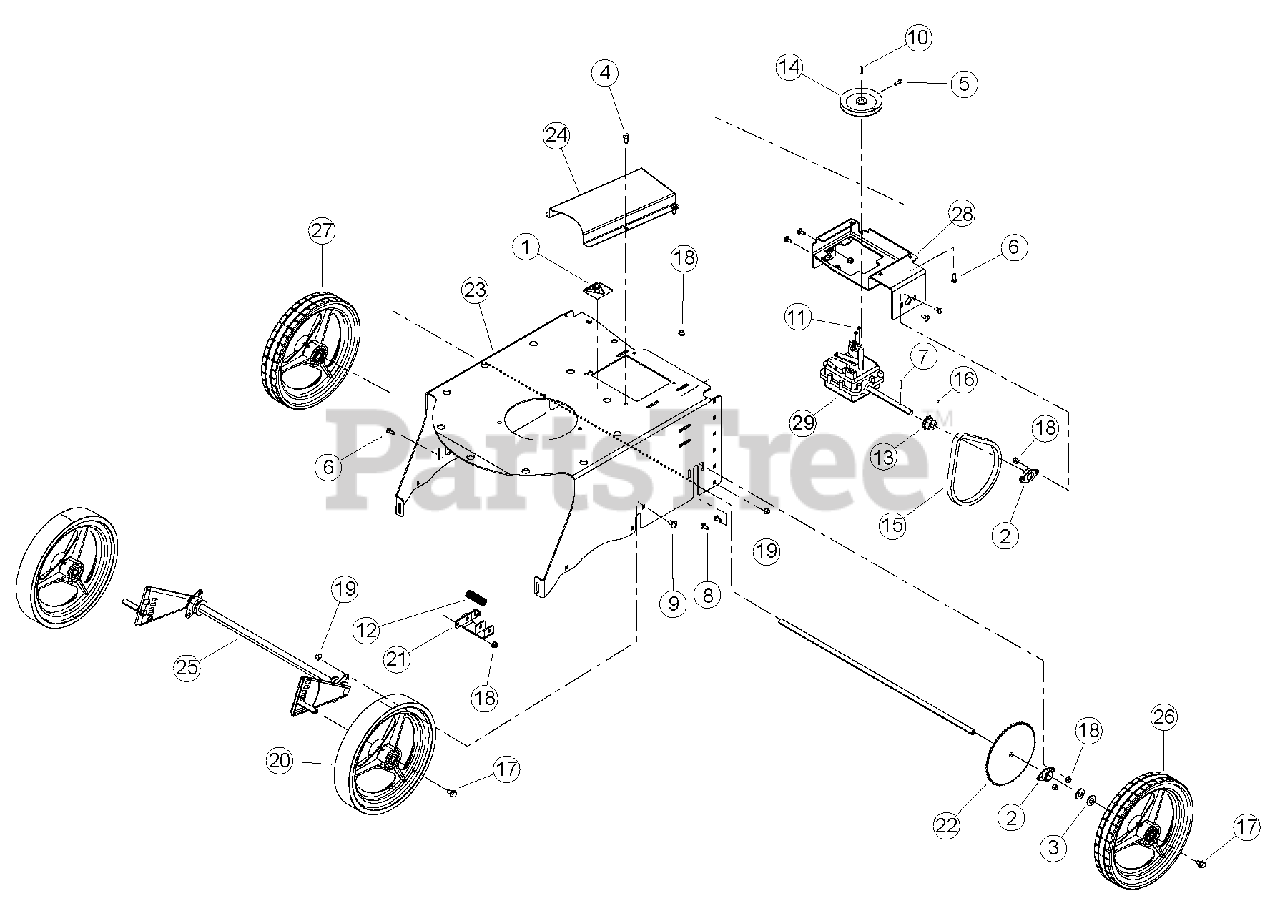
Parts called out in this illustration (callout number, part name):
1	DECAL, SHIELD DANGER
2	BEARING, 1/2 FLANGE
3	WASHER, 1/2 SAE FLAT
4	SCREW, 11/32 X 7/8 HWH AB THREAD
5	SCREW, 1/4 X 5/8 SQ HD SET
6	BOLT, 1/4 X 3/4 CRG
7	PIN, 1/8 X 7/8 SPRING
8	BOLT, 1/4 X 5/8 CRG
9	BOLT, 5/16 X 5/8 CRG
10	KEY, 4 MM SP X 20 MM
11	WASHER, #6 SAE FLAT
12	SPRING, COMPRESS LC-072J-6
13	SPROCKET, 35 B10
14	PULLEY, 4 O.D. X 12 MM BORE
15	CHAIN, #35 X 62 PITCH W/ CONN. LINK
16	SCREW, #8-32 X 3/16 KNR CUP PT
17	BOLT, 5/16-18 X 1/2 GR5 HH SER/FLN
18	NUT, 1/4-20 NYLOCK FLANGE
19	NUT, 5/16-18 NYLOCK FLANGE
20	WHEEL ASSEMBLY, BEARVAC PUSH
21	WELDMENT, BEARVAC HEIGHT ADJ.
22	WELDMENT, SP LONG AXLE
24	GUARD, BEARVAC BELT
25	WELDMENT, AXLE PIVOT
26	WHEEL, BEARVAC SP LEFT
27	WHEEL, BEARVAC SP RIGHT
28	WELDMENT, TRANSMISSION MOUNT
29	TRANSMISSION, 3 SPEED BEARVAC
